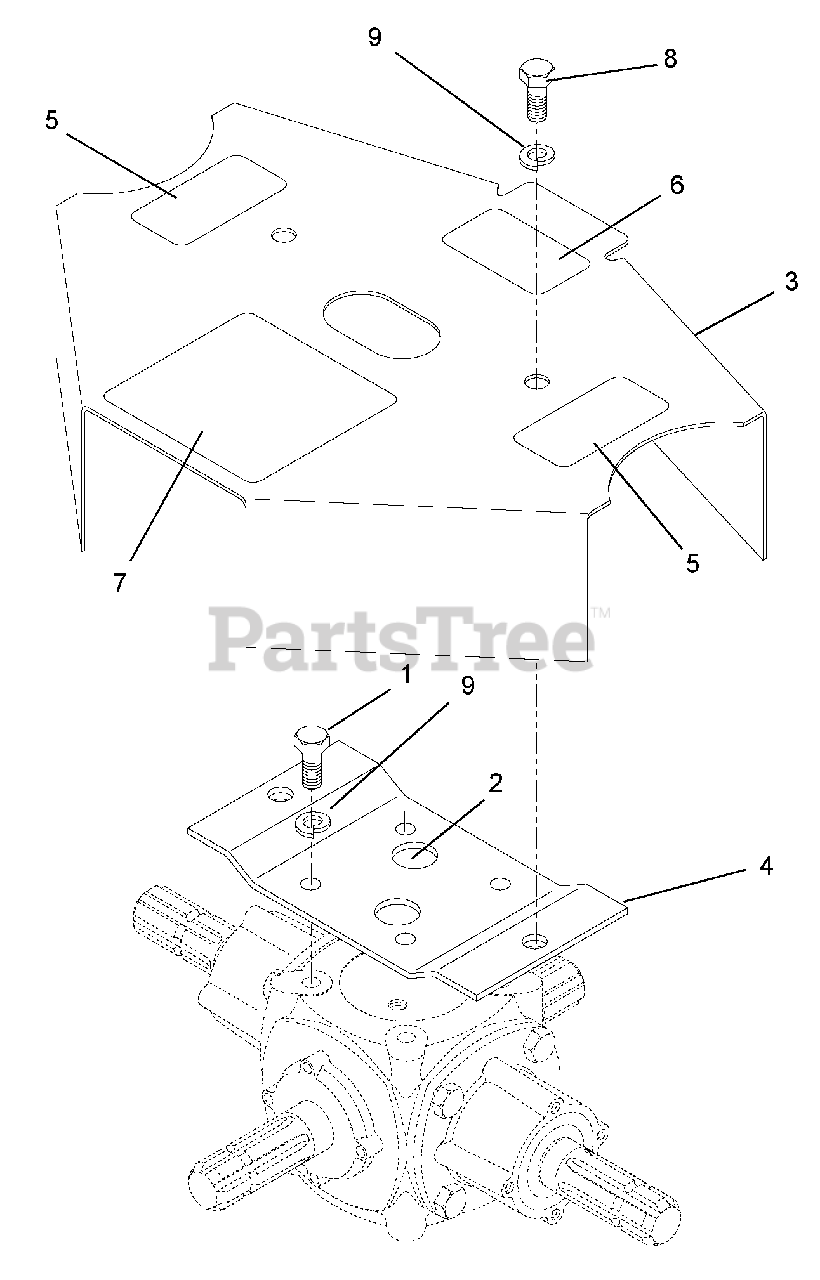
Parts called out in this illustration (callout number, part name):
1	Cap Screw, M12 x 1.75 x 25
3	Shield With Decals
4	Weldment, Shield Mount
5	Decal, Warning
6	Decal, Warning
7	Decal, Warning
8	Cap Screw, Hex Head .50-13 x 1
9	Washer, Lock .50
